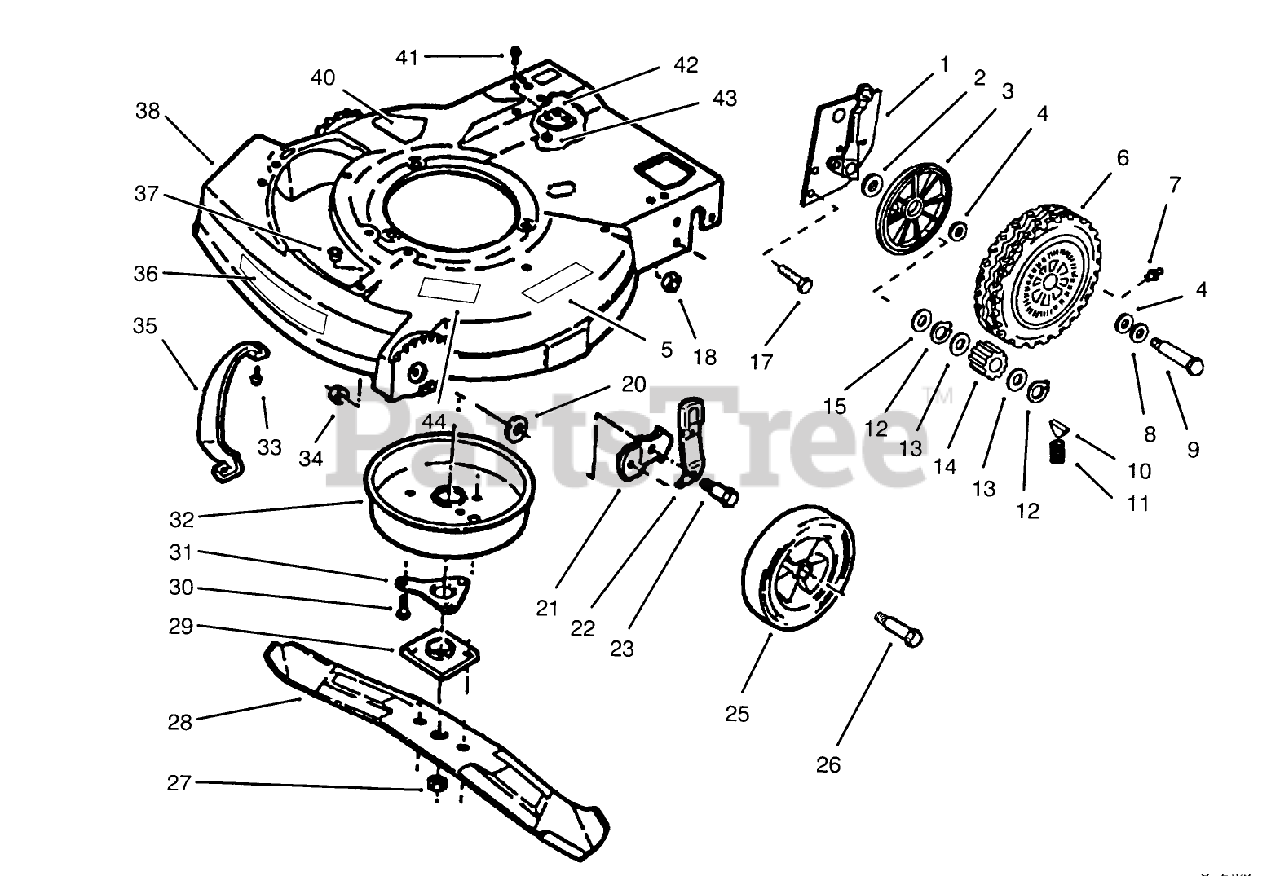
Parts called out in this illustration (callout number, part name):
4	WASHER-FELT
5	DECAL-WARNING
7	FITTING LINCOLN
9	BOLT WHEEL
12	RET RING
13	SPACER/GR ALGHNY
14	PINION BROCKWAY
15	THRUST WASHER
17	SCREW - HEX
18	NUT-LOCK, NI
22	SPRING ARM ASM
26	BOLT-SHOULDER
27	NUT-BLADE
29	PLATE AND COLLAR ASM
31	SUPPORT F
32	MUFFLER COVER F
33	SCREW-HWH
34	NUT-LOCK, NI
35	BAR-TOE
38	HOUSING W/DECALS
40	DECAL-DANGER
42	BOLSTER
43	NUT-LOCK, NI
